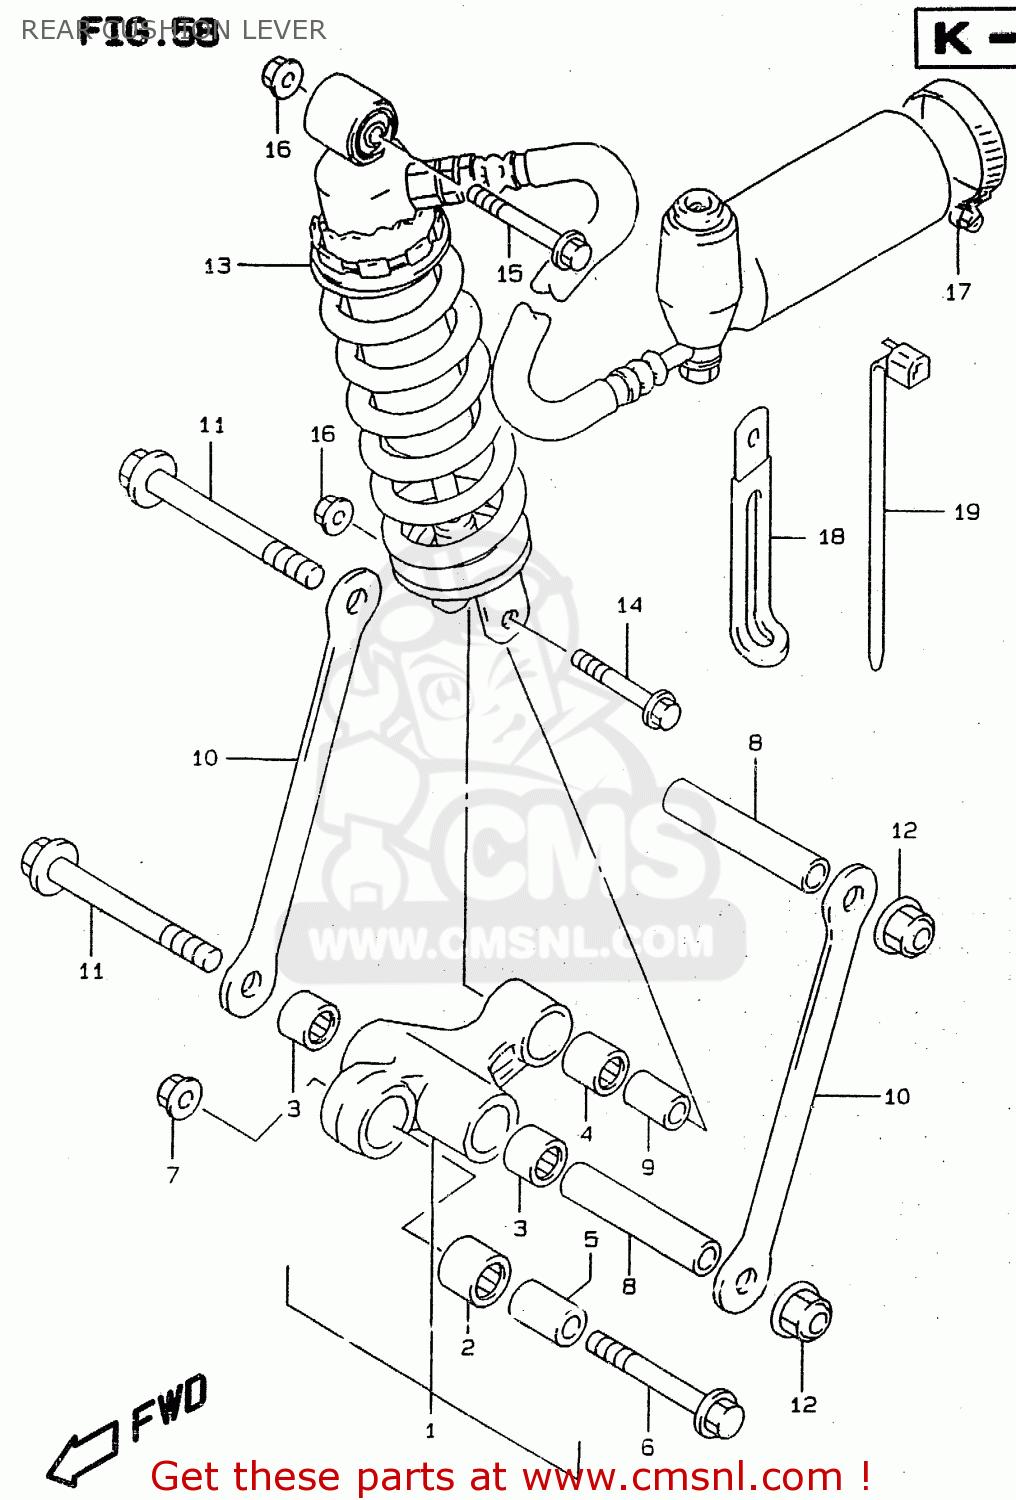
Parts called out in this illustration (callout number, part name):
1	LEVER SET,RR CUSHION
2	BEARING(20X27X26)
3	BEARING(17X24X25)
4	BEARING(17X24X26)
5	SPACER,RR CUSHION LEVER FR
6	BOLT,CUSHION LEVER FR
7	NUT 12MM
8	SPACER(12X17X85)
9	SPACER,RR CUSHION LEVER
10	ROD,REAR CUSHION LEVER
11	BOLT(12X115)
12	NUT 12MM
13	ABSORBER ASSY,RR SHOCK
14	BOLT(10X58)
15	BOLT(10X50)
16	NUT
17	CLAMP
18	CLAMP
19	CLAMP L:165
